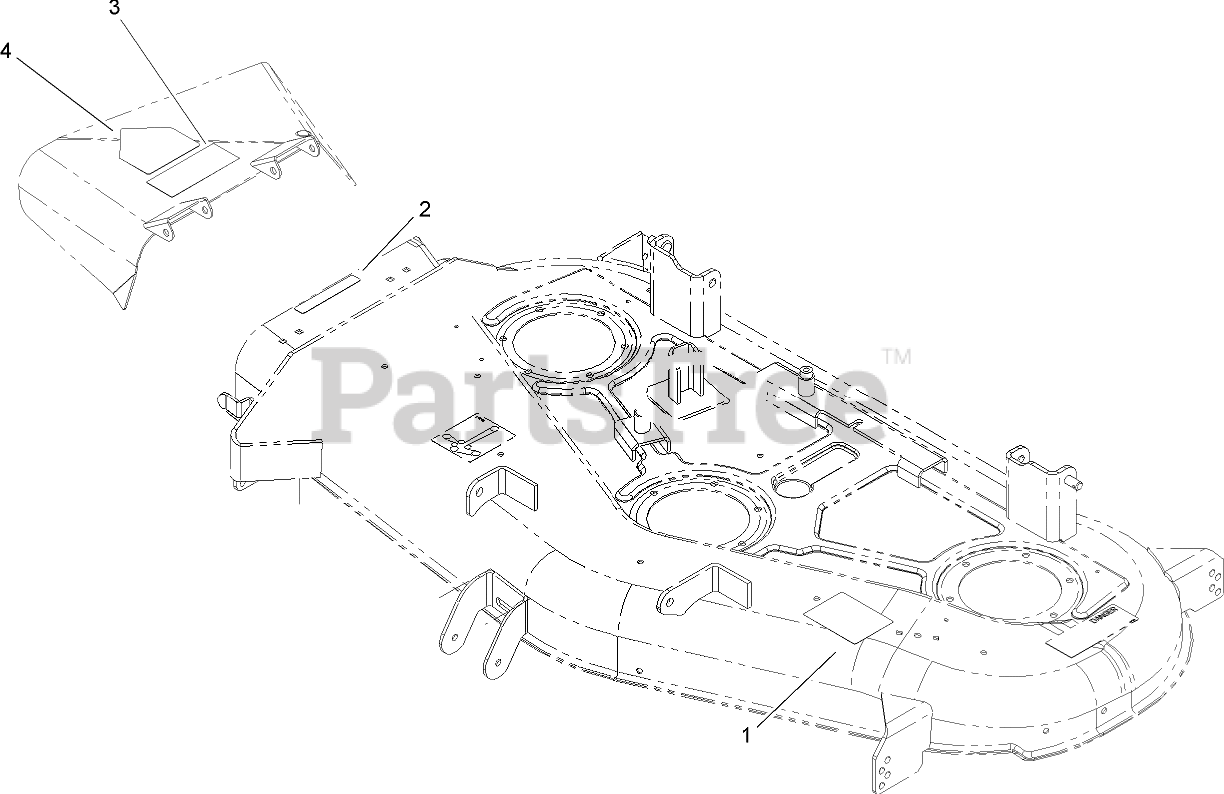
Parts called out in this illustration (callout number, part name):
1	DECAL-ANTI SCALP
2	DECAL-DANGER
3	DECAL-DANGER
4	DECAL-DANGER
